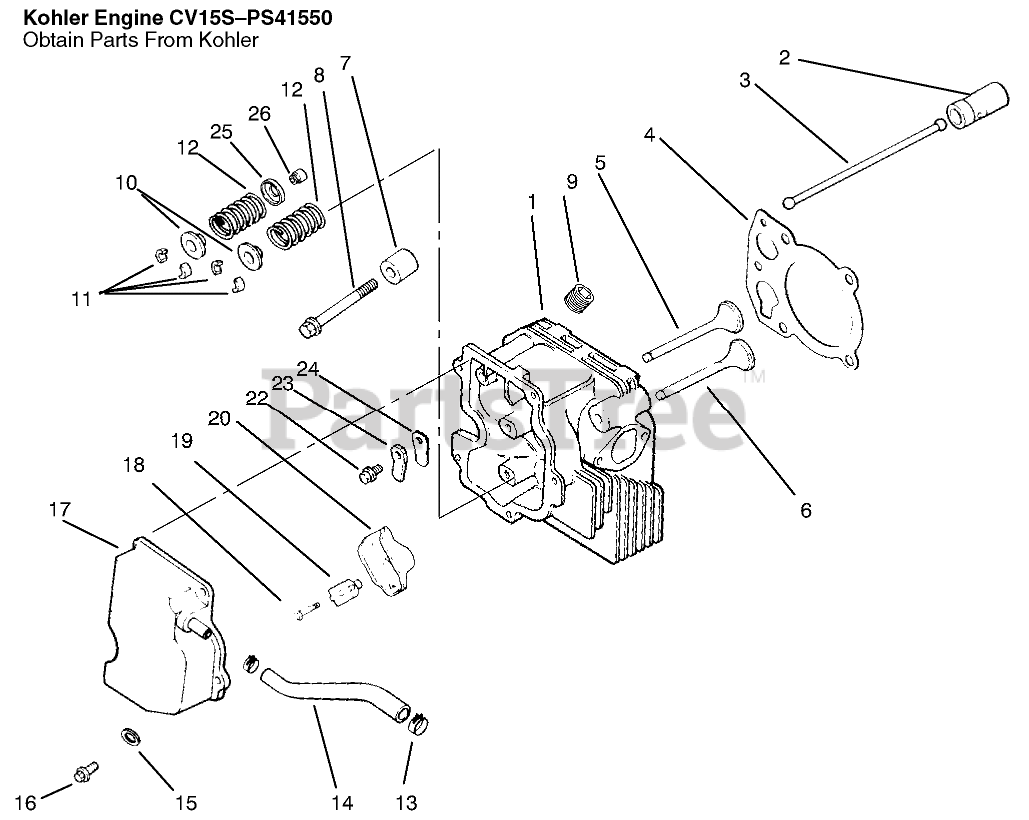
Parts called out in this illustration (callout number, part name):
1	Cylinder Head
2	Lifter-Valve
3	Rod-Push
4	Gasket-Cylinder Head
5	Valve-Intake STD
5	Valve-Intake .25
6	Valve-Exhaust STD
6	Valve-Exhaust .25
7	Spacer-Head Bolt
8	Screw M10x1.5x80
9	Plug
10	Cap-Spring, Valve
11	Retainer Kit
12	Spring-Valve
13	Clamp
14	Hose-Breather
15	Washer
16	Screw
17	Cover-Valve w/Nipple
19	Pivot-Rocker Arm
20	Arm-Rocker
22	Screw
23	Retainer-Reed
24	Reed-Breather
25	Retainer-Spring
26	Seal-Stem, Valve
